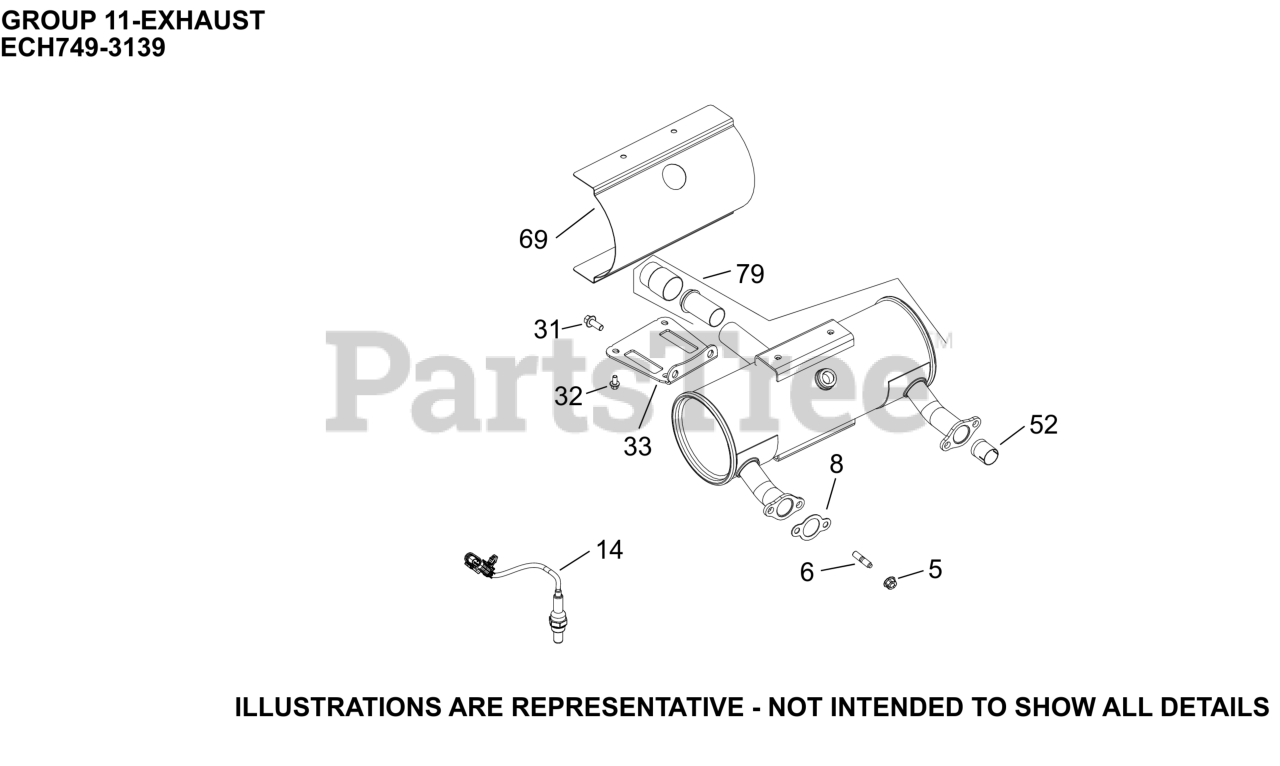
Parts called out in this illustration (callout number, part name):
5	NUT, HEX FLANGE LOCK (M8)
6	STUD, METRIC EXHAUST
8	GASKET, EXHAUST MANIFOLD
14	SENSOR, OXYGEN (M18 x 1.5 THREADS)
31	SCREW, FLG M8X1.25X20
32	SCREW, FLG M6X1.0X12
33	BRACKET, MUFFLER
52	LINER, EXHAUST PORT
69	SHIELD, HEAT
79	MUFFLER ASSEMBLY
